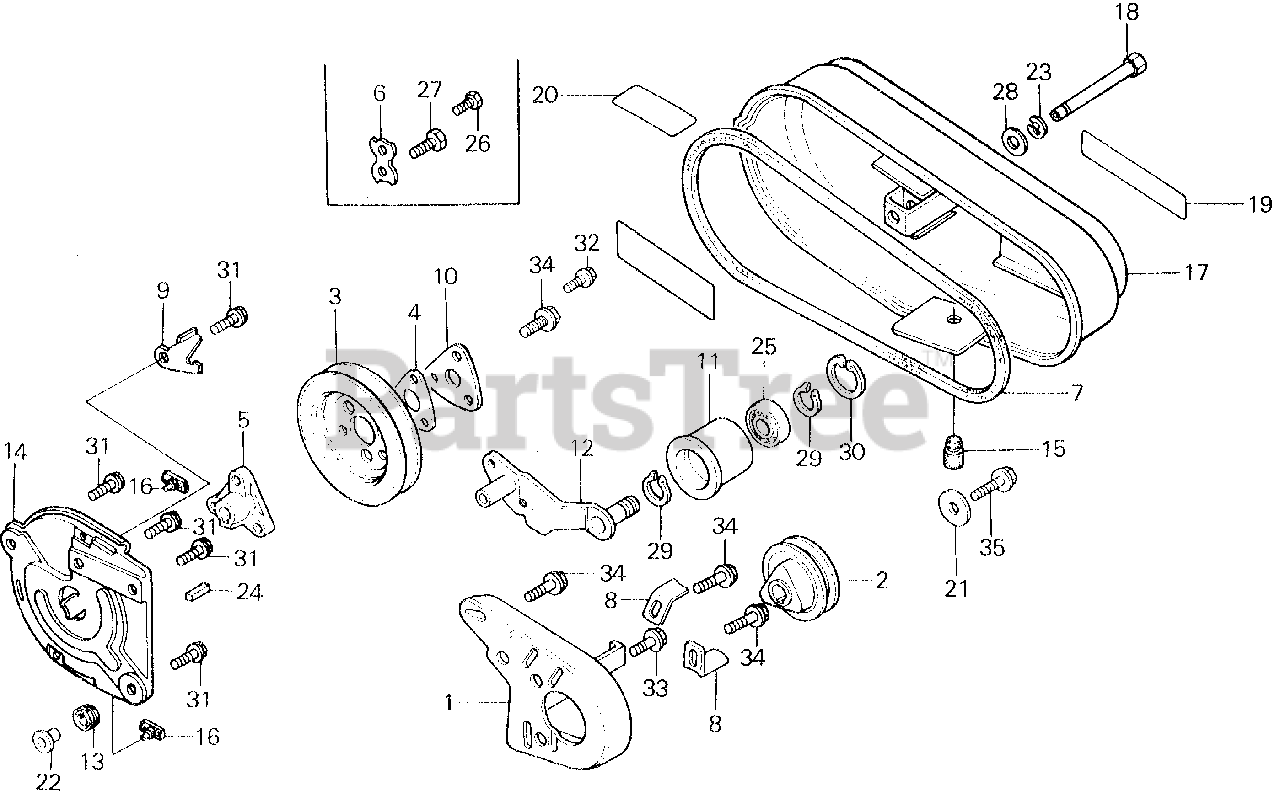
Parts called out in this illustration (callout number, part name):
1	PLATE, ENGINE ADJUSTING
2	PULLEY, DRIVEN (80MM)
3	PULLEY (125MM)
4	SPACER, PULLEY (NOT AVAILABLE)
5	BOSS, DRIVEN PULLEY (NOT AVAILABLE)
6	WASHER, LOCK
7	V-BELT (35)
8	STOPPER E, BELT
9	STOPPER F, BELT
10	PLATE, PULLEY
11	ROLLER, TENSIONER
12	ARM, TENSIONER
13	GROMMET, WIRE HARNESS
14	STAY, BELT COVER
15	STOPPER, TENSIONER ARM
16	GROMMET, BELT COVER
17	COVER, BELT *NH31* (MCKINLEY WHITE)
17	COVER, BELT *NH31* (MCKINLEY WHITE) (NOT AVAILABLE)
18	LATCH, BELT COVER
19	MARK, BELT COVER (NOT AVAILABLE)
20	CAUTION, BELT COVER (ENGLISH)
21	WASHER (8MM)
22	WASHER, NUMBER BRACKET MOUNTING
23	E-RING (9MM)
24	KEY, FLAT (4X4X14)
25	BEARING, RADIAL BALL (6202G)
26	BOLT, HEX. (6X16)
27	BOLT, HEX. (8X16)
28	WASHER, PLAIN (10MM)
29	CIRCLIP, OUTER (15MM)
30	CIRCLIP (INNER) (35MM) (NOT AVAILABLE)
31	BOLT, FLANGE (6X12)
32	BOLT, FLANGE (6X16)
33	BOLT, FLANGE (8X12)
34	BOLT, FLANGE (8X16)
35	BOLT, FLANGE (8X28)
